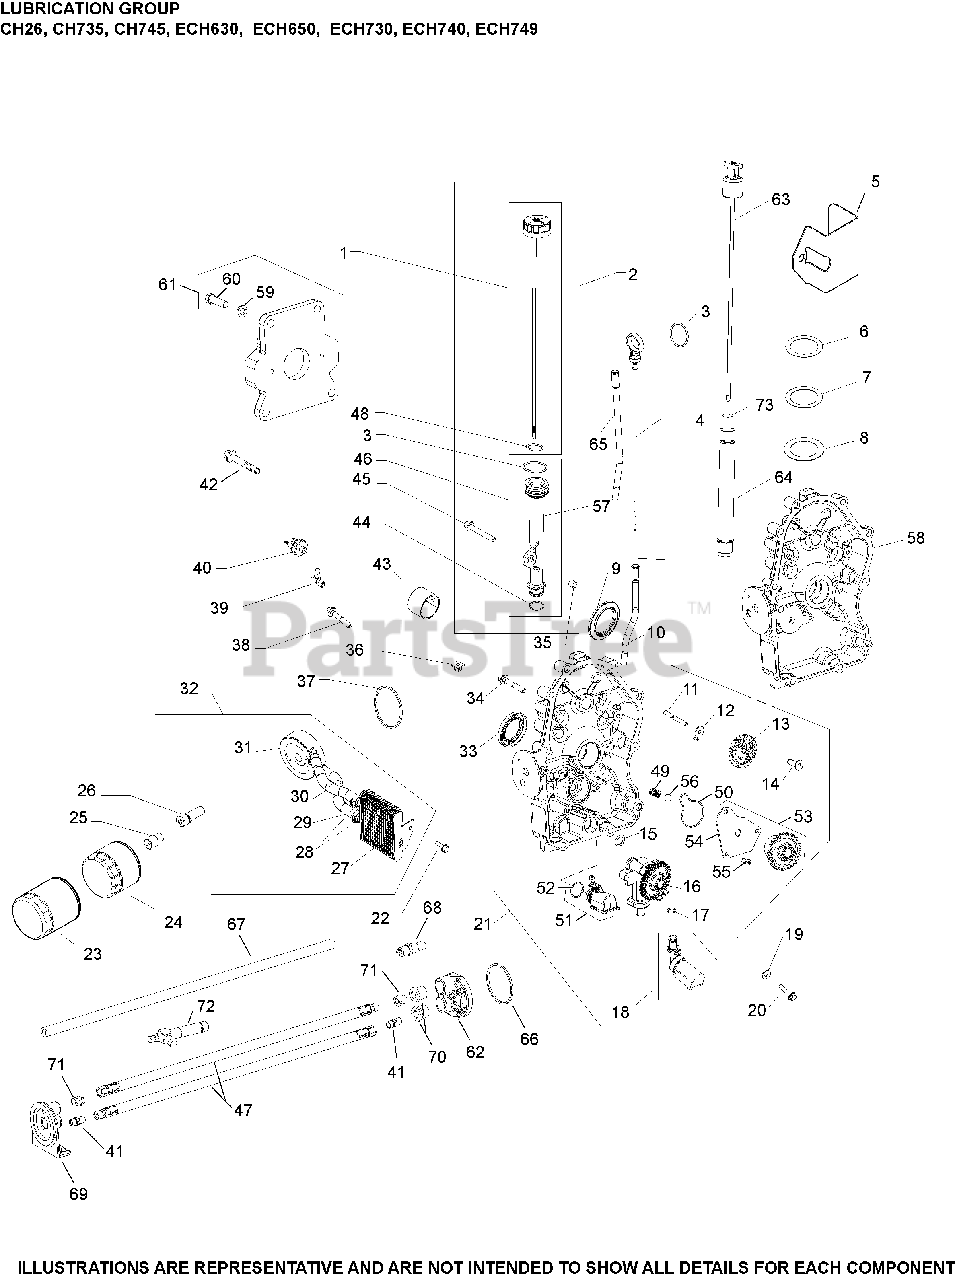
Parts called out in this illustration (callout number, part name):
10	KIT, DIPSTICK/DIPSTICK TUBES
11	SHAFT, GOVERNOR GEAR
12	TAB, LOCKING
13	KIT, GOVERNOR GEAR W/PIN
14	PIN, GOVERNOR REGULATING
21	KIT, CLOSURE PLATE
23	OIL FILTER
25	NIPPLE, OIL FILTER
33	SEAL, OIL
35	PLUG, CTSK PIPE 1/8"
38	SCREW, FLG M8X1.25X45
40	SENSOR, OIL PSI
49	SPRING, COMPRESSION
50	SEAL, OIL PUMP COVER
51	PICK-UP ASSEMBLY, OIL
52	O-RING, OIL PICK-UP
53	PUMP ASSEMBLY, OIL
54	COVER, OIL PUMP
55	SCREW, BUTTON HEAD
56	PRESSURE RELIEF BALL
